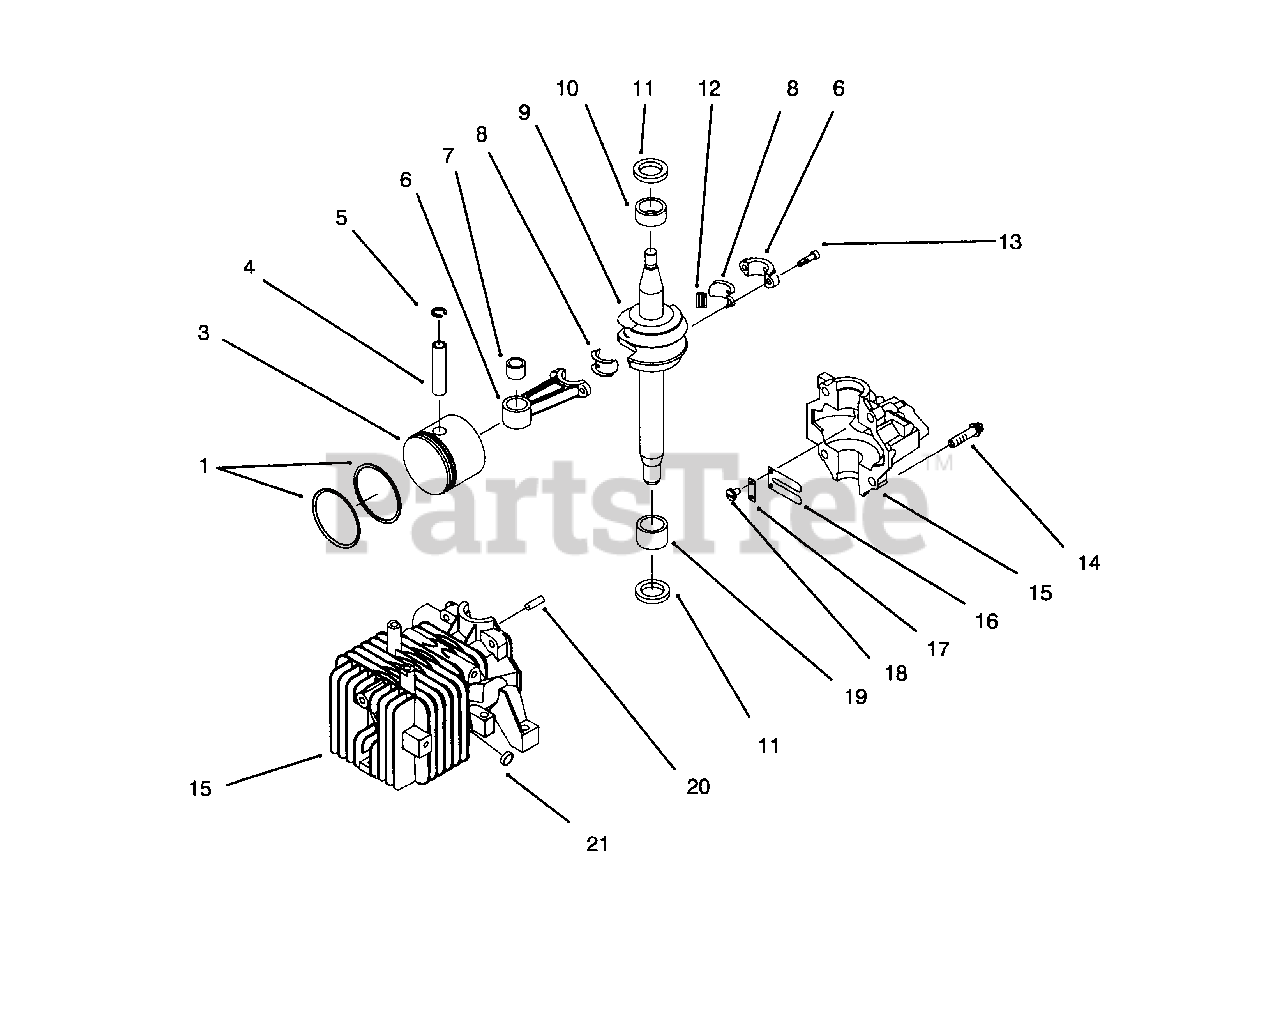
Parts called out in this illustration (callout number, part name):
1	Set-Ring
4	Pin-Wrist
5	Ring-Retaining
6	Connecting Rod Assembly
8	Liner-Split (Set of 2)
9	Crankshaft
10	Bearing-Upper Main
11	Seal-Oil
12	Bearing-Needle
13	Screw-Hex. Hd.
14	Screw-Torx. Washer Hd.
15	Cylinder & Crankcase Ass'y
16	Reed-Carburetor
17	Reed-Backup Plate
19	Bearing-Needle
21	Plug-Core
